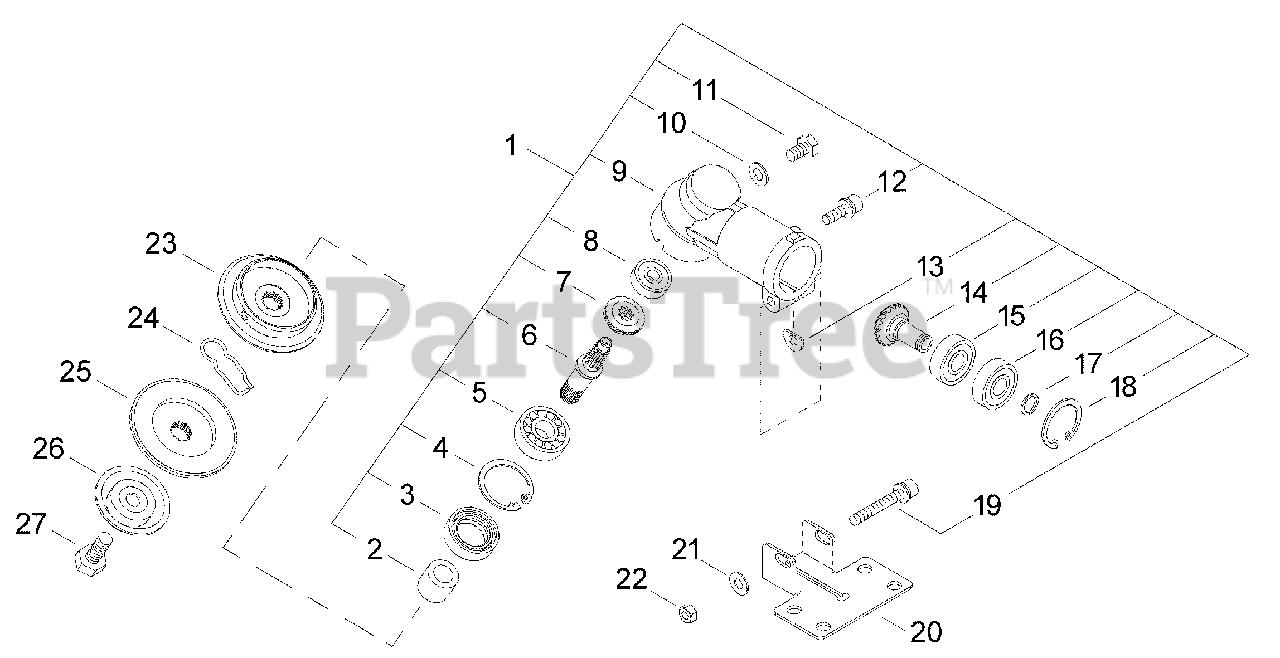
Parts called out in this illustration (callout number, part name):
1	GEAR CASE ASSY
2	COLLAR
3	SEAL, OIL
4	RING, RETAINING - 32
5	BEARING, BALL - 6201
6	GEAR - SHAFT
7	GEAR - BEVEL
8	BEARING, BALL - 609
9	CASE, GEAR
10	WASHER
11	BOLT - 6X10
12	SCREW - 5X16
13	SHIM
14	PINION SET
15	BEARING, BALL - 6901
16	BEARING, BALL - 6901ZZ
17	RING, RETAINING
18	RING, RETAINING - 24
19	SCREW - 6X40
20	BRACKET
21	WASHER - 6
22	NUT - 6
23	HOLDER - A
24	CLIP
25	HOLDER
26	GUARD
27	BOLT - 8 -- LEFT HAND
